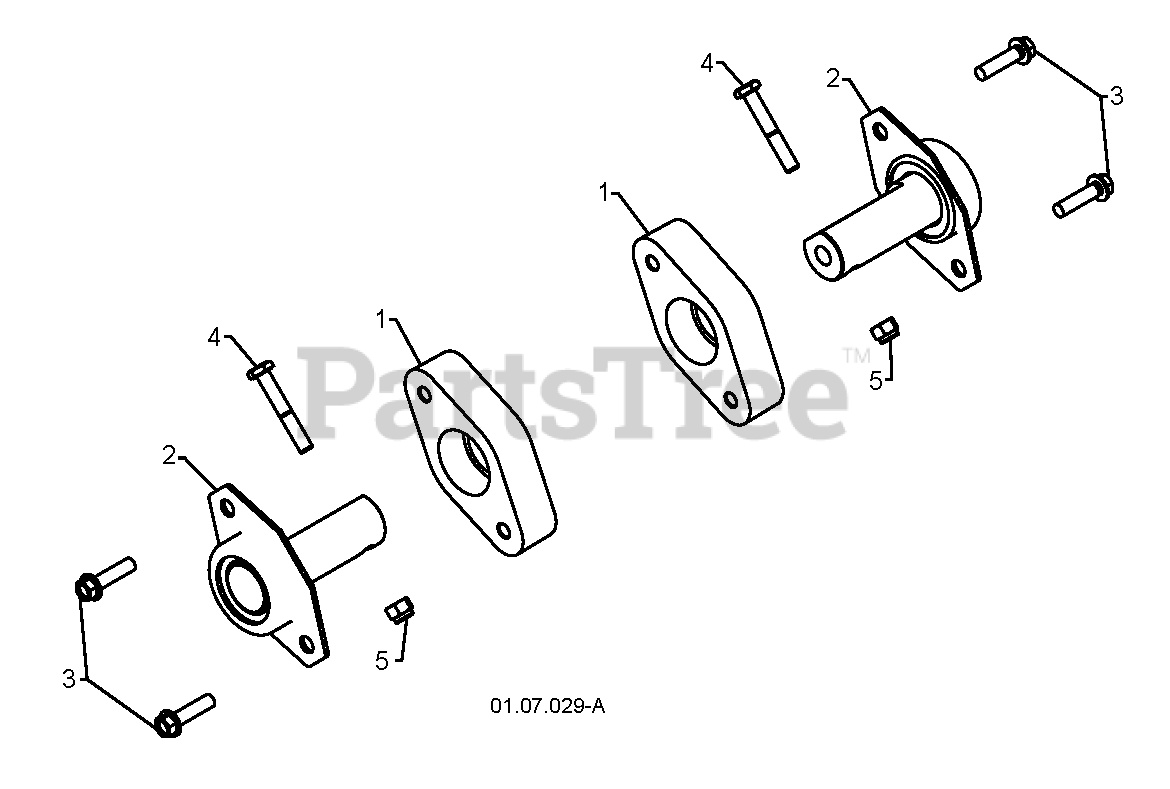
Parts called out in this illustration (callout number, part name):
1	BEARING RETAINER, PLASTIC
2	BEARING.BALL.AUGER.FLAT.
3	SCREW, HEX HD 5/16X1
4	SCREW.HEX.HD1/4-20X
5	LOCKNUT.NYLOC.1/4-20
